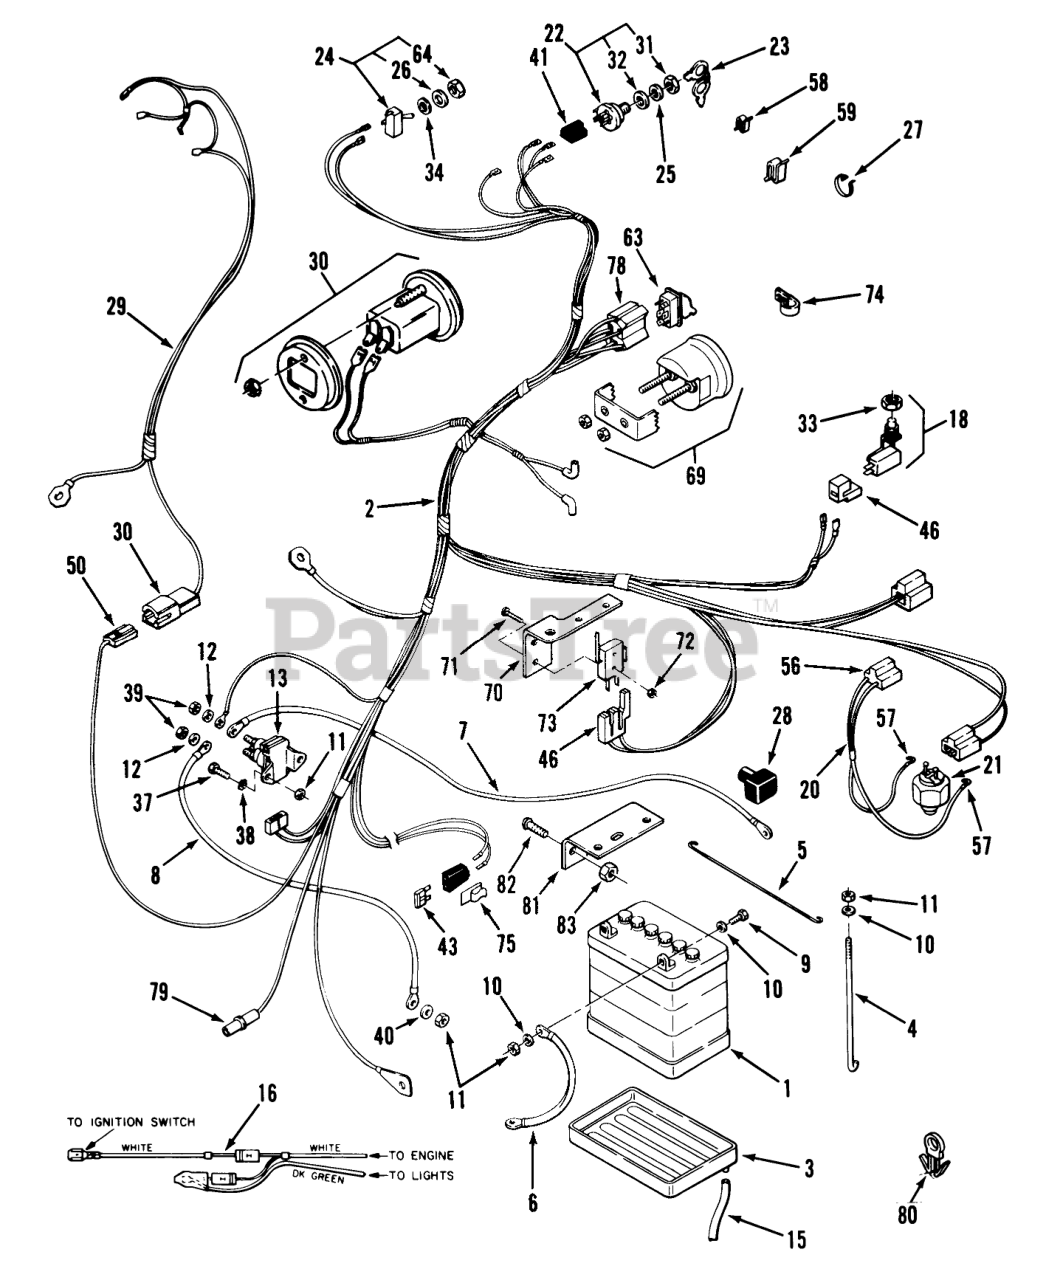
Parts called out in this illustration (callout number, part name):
1	Battery
2	Harness Wire (Incl. Ref. #14, 41, 46, 78 & 79)
3	TRAY-BATTERY
5	ROD-BATTERY HOLD DWN
6	WIRE -BLACK
7	WIRE - 14" BLACK
8	ASSY WIRE
9	SCREW-HH
10	WASHER-FLAT
11	NUT-HEX
12	Washer
13	Solenoid (Incl. Ref. #11)
15	TUBE-BATTERY DRAIN
16	DIODE-KIT SERVICE
18	Seat Switch
20	ASSY WIRING HARNESS
21	SWITCH (N.C.-TRANS)
22	Switch-Ignition (Incl. Ref. #31-32)
23	Ignition Key
24	Switch-Light (212-5 & 212H) (Incl. Ref. #26, 34 & 64)
25	Washer
26	Washer
27	PLASTIC TIE
28	Boot
29	HARNESS-HEADLIGHT
30	Hourmeter
32	LOCKWASHER
33	WASHER-LOCK/EXT
34	TAB-WASHER
37	Screw
38	WASHER-LOCK
39	NUT-JAM
40	WASHER-LOCK
41	CONNECTOR-5 WAY-SERV
43	FUSE-BLADE, 15 AMP
46	CONNECTOR BODY
50	CONNECTOR BODY ELECT
56	CONNECTOR BODY B
57	TERMINAL-TAB RCPT
58	CLIP
59	SPEED CLIP
63	PTO-SWITCH W/COVER
69	Voltmeter (Incl. 109650 Clamp & 5924 #10-32 Nut, 2 Req.)
70	BRKT-SWITCH R
71	Screw
72	NUT HEX 4-40 ELAST
73	SWITCH - CLUTCH
74	CLAMP
78	CONNECTOR 5 WAY
80	CLIP-SNAP IN
81	BRKT-FUSE HOLDER B
82	Screw
83	NUT-LOCK, NI
